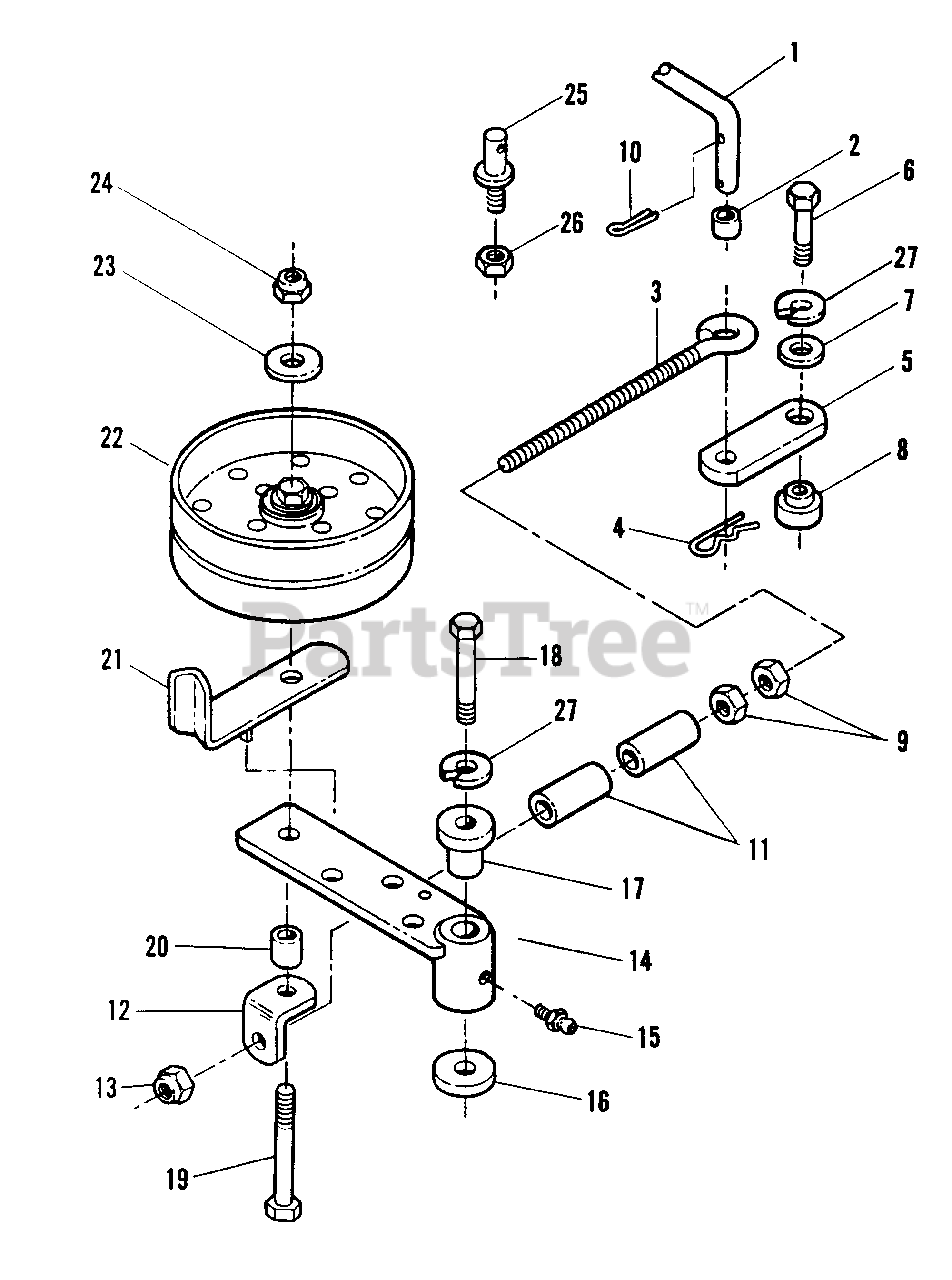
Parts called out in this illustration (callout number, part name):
1	LINK, Blade Engage
2	SLEEVE, Linkage
3	LINK, Blade Engage
4	PIN, #13 Hair
5	LINK, Blade Assist
6	SCREW, 3/8" x 1 1/2 Lg. Hex Cap
7	FLAT WASHER, 3/8"
8	SPACER, Pivot
9	NUT, 3/8" - 16 Hex
10	PIN, 3/32" x 1" Lg. Cotter
11	BUSHING
12	ANGLE, Blade Engage
13	NUT, 3/8" - 16 Nyloc
14	WELDMENT, 36" Idler
15	GREASE Fitting., 1/4" - 28 Str. Zerk
16	MACHINE BUSHING, 14 GA. 1
17	SPACER, Pivot
18	SCREW, 3/8" C x 3" Lg. Hex. Cap, GR. 5
19	SCREW, 3/8" x 2 1/2" Lg. Hex. Cap
20	SPACER, Blade Link
21	BELT GUIDE
22	PULLEY, Idler 5.0
23	FLATWASHER, 3/8"
24	NUT, 3/8" C Nyloc
25	STUD
26	NUT, 3/8" Hex.
27	LOCKWASHER, 3/8" Split
